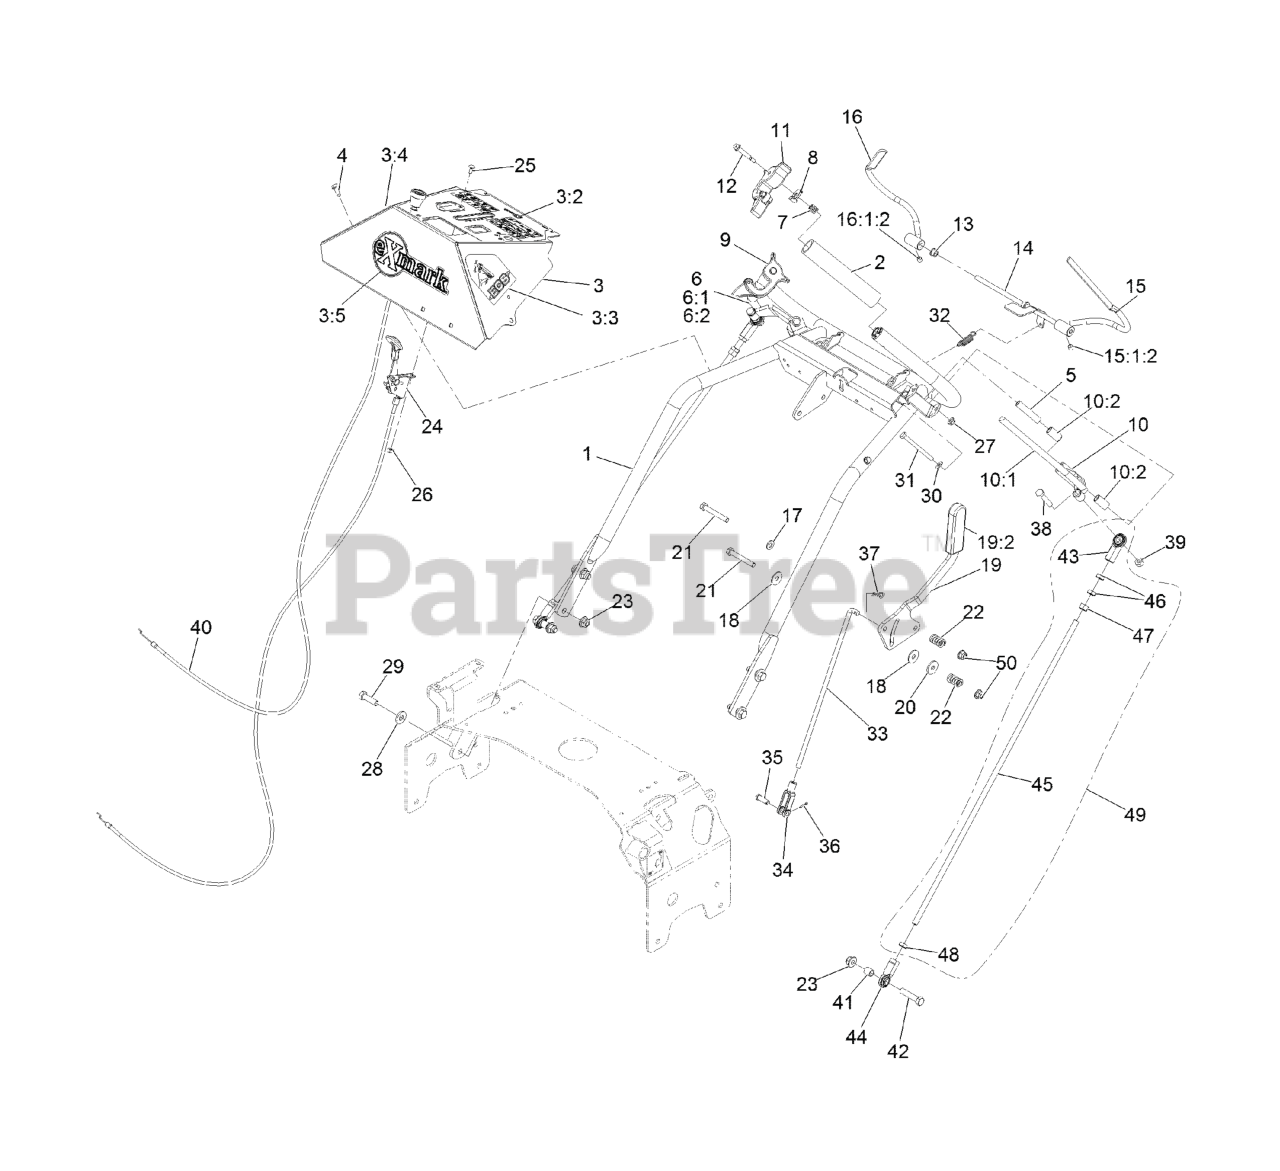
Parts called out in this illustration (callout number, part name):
1	WELD, HANDLE
2	GRIP-BAR, HANDLE
3	ASM, CONSOLE W/ DECALS
3:2	DECAL-CONSOLE
3:3	DECAL,LH ECS INSTRUCTION
3:4	DECAL,RH ECS INSTRUCTION
3:5	DECAL, EXMARK LOGO
4	SCREW-HWH
5	BUSHING-LEVER, DRIVE
6	DRIVE LEVER-ASM, RH
6:1	WLD,RH DRIVE LEVER
6:2	BUSHING, SLEEVE
7	SPRING-TANK, FUEL
8	LATCH, ECS
9	ASM,LATCH RH THUMB
10	DRIVE LEVER-ASM, LH
10:1	WLD,LH DRIVE LEVER
10:2	BUSHING, SLEEVE
11	ASM,LATCH LH THUMB
12	SCREW-SHOULDER
13	BUSHING-NYLON
14	WLD,OPC LEVER AXLE
15	WLD,LH OPC LEVER
15:1:2	SCREW-SET
16	WLD,RH OPC LEVER
16:1:2	SCREW-SET
17	WASHER-PLAIN
18	WASHER-FRICTION
19	LEVER, SHIFT W/GRIP
19:2	GRIP-HANDLE, STEERING
20	WASHER-FRICTION
21	SCREW-HH
22	SPRING-COMPRESSION
23	NUT-HF, NI
24	CONTROL-THROTTLE
25	BOLT-CARR
26	NUT-LOCK, NI
28	WASHER-BELLEVILLE
29	SCREW-HH
30	WASHER-FLAT
31	SCREW-HH
32	SPRING-EXTENSION
33	ROD,SPEED CONTROL
34	YOKE-ADJUSTABLE
35	PIN-CLEVIS
36	PIN-COTTER
37	PIN-COTTER
38	SCREW-HH
39	NUT-LOCK, NI
40	CABLE, CHOKE
41	SPACER-TUBE, PUMP LINK
42	SCREW-HH
43	JOINT-BALL, END
44	JOINT-BALL END, LH
45	LINK,DRIVE (PLTD)
46	NUT-HJ
47	NUT-HEX
48	NUT-HEX JAM, LH
49	DRIVE LINK ASM
50	NUT-HF, NI
